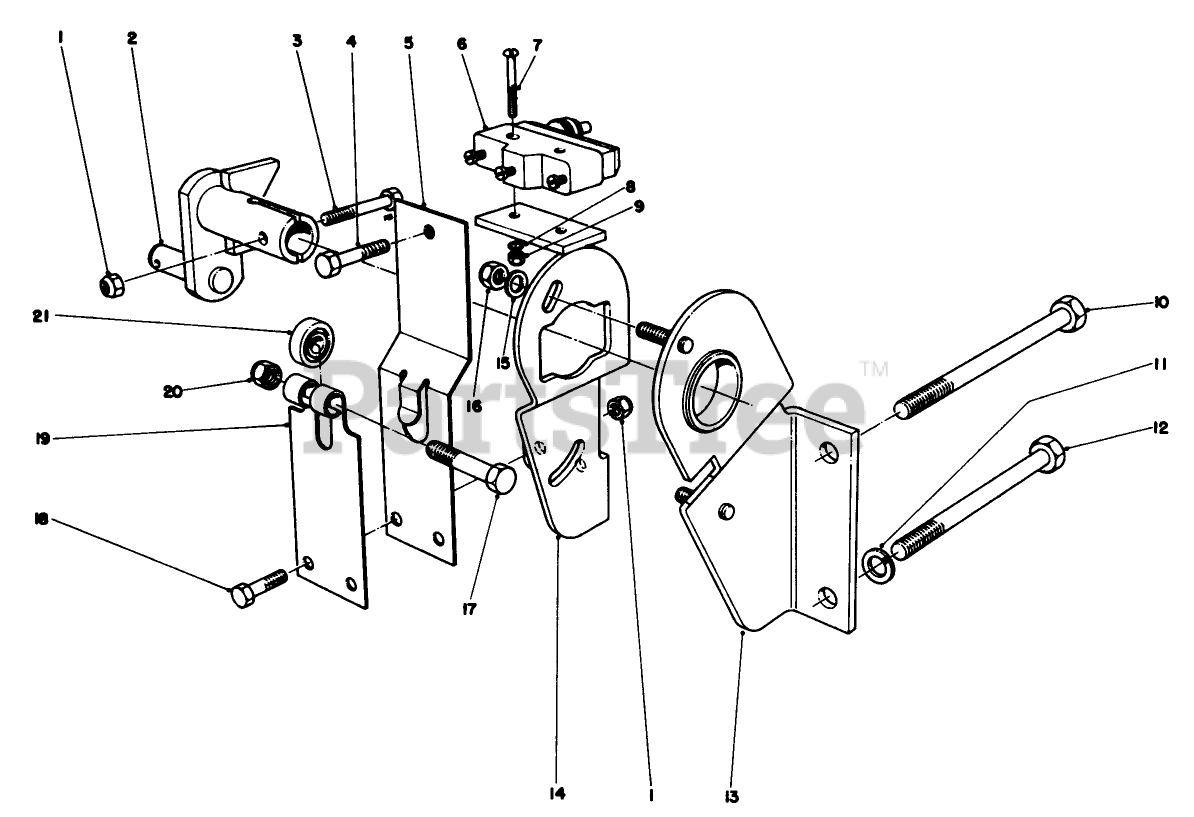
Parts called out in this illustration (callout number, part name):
1	NUT-LOCK, NI
3	SCREW-HH
4	SCREW-HH
5	EXTENDED LEAF SPRING ASM
7	SCREW-MACHINE
8	WASHER-LOCK, INTERNAL
9	NUT-HEX
10	SCREW-HH
11	WASHER-LOCK
12	SCREW-HH
13	MTG BRKT WA *B
16	NUT-LOCK
17	SCREW-HH
18	SCREW-HH
20	NUT-LOCK, NI
21	BEARING-BALL
